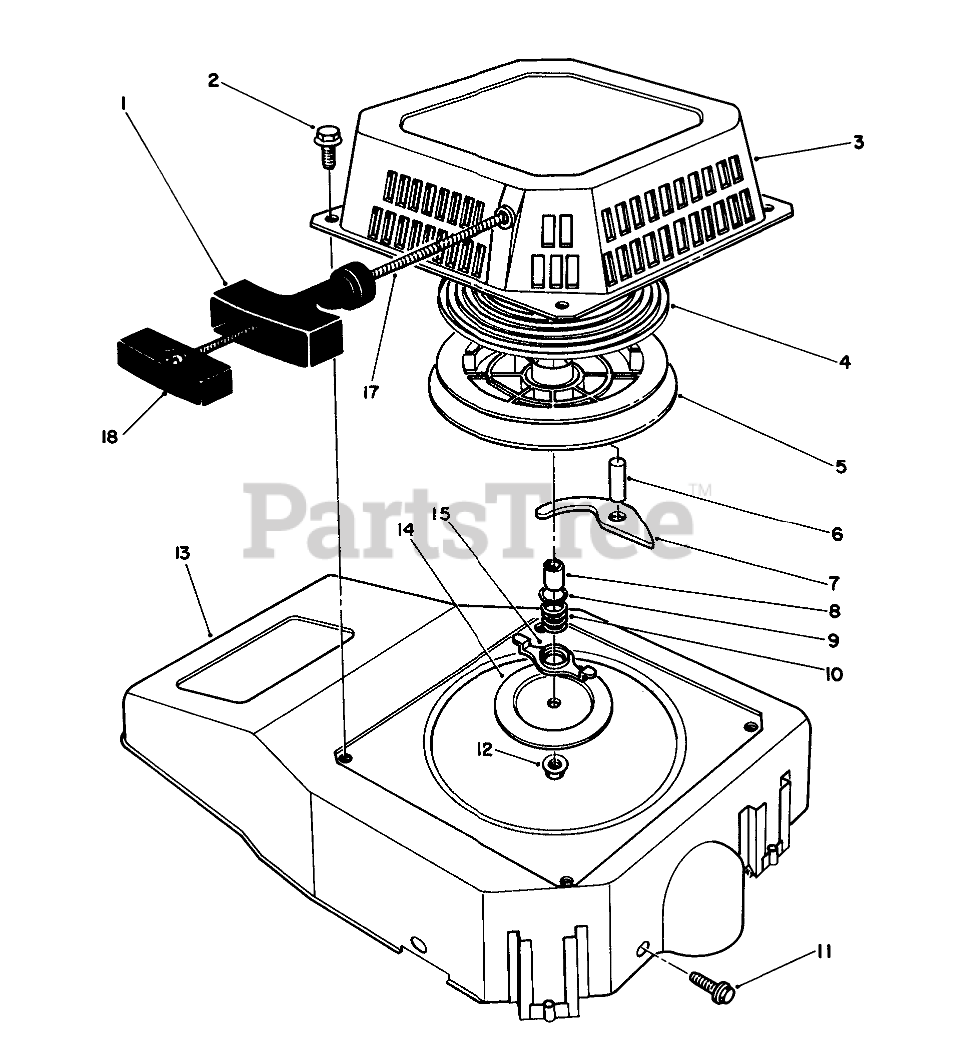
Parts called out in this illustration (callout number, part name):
1	HANDLE
2	SCREW-HHF
3	Case-Recoil
4	SPRING
8	Spacer
9	WASHER
10	Spring-Friction
13	SHROUD
14	PLATE
15	Guide-Paw
17	ROPE-STARTER
18	RETAINER HANDLE
